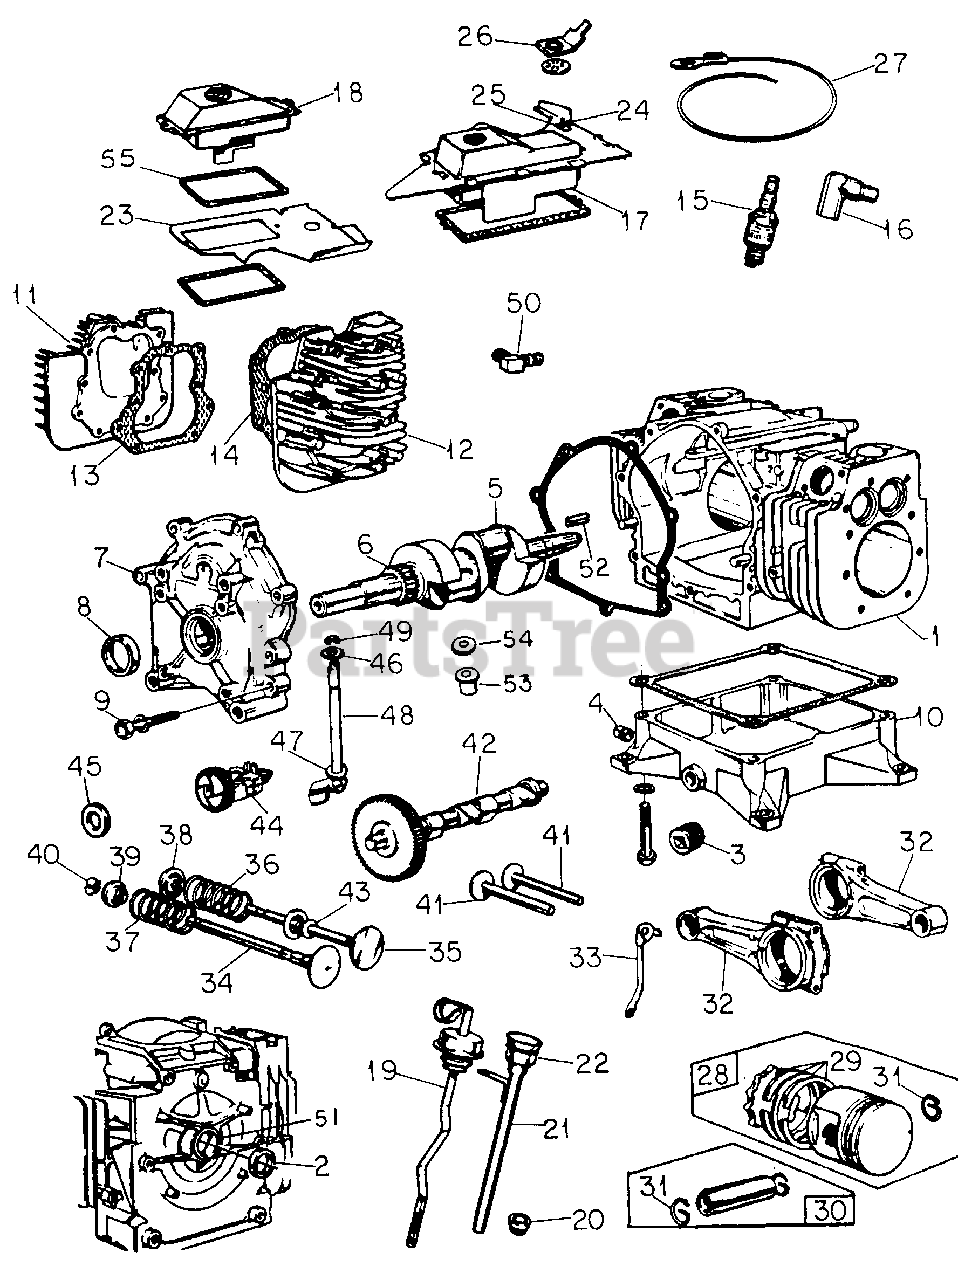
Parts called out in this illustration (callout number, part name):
1	Crankcase Assy
2	Seal, Oil
3	Plug, Oil Drain
4	Plug, Oil Drain
5	Crankshaft Assy
6	Gear, Timing
7	Cover Assy, Crankcase End
8	Seal, Oil
9	Screw, Cover Mtg
10	Base, Engine
11	Head, Cylinder #1
12	Head, Cylinder #2
13	Gasket, Cylinder Head #1
14	Gasket, Cylinder Head #2
15	Plug, Spark
16	Cover, Spark Plug Elbow
17	Breather Assy
18	Breather Assy
19	Gauge, Oil Dipstick
20	Seal, Filler Tube
21	Tube, Oil Filler & Gauge
22	Seal, Oil Filler Tube
23	Guide, Air
26	Terminal, Spade
27	Cable, Ground
28	Piston Assy, Std
29	Ring Set, Piston, Std
30	Pin Assy, Piston, Std
31	Ring, Piston Pin Lock
32	Rod Assy, Connecting
33	Oiler, Connecting Rod Dipper
34	Valve, Exhaust
35	Valve, Intake
36	Spring, Intake Valve
37	Spring, Exhaust Valve
38	Retainer, Intake Valve
39	Retainer, Exhaust Valve
40	Keeper, Exhaust Valve
41	Tapper, Valve
42	Camshaft w/Gear Assy
43	Seal Assy, Retainer
44	Gear, Governor
45	Washer, Thrust
46	Washer, Governor Crank
47	Washer, Governor Crank
48	Crank, Governor
49	Ring, E-Retaining
50	Elbow, Fuel Connector
51	Bearing Assy, Cylinder
52	Key, Flywheel
53	Bushing, Lower Governor
54	Seal, Governor Shaft
55	Gasket, Valve Cover
